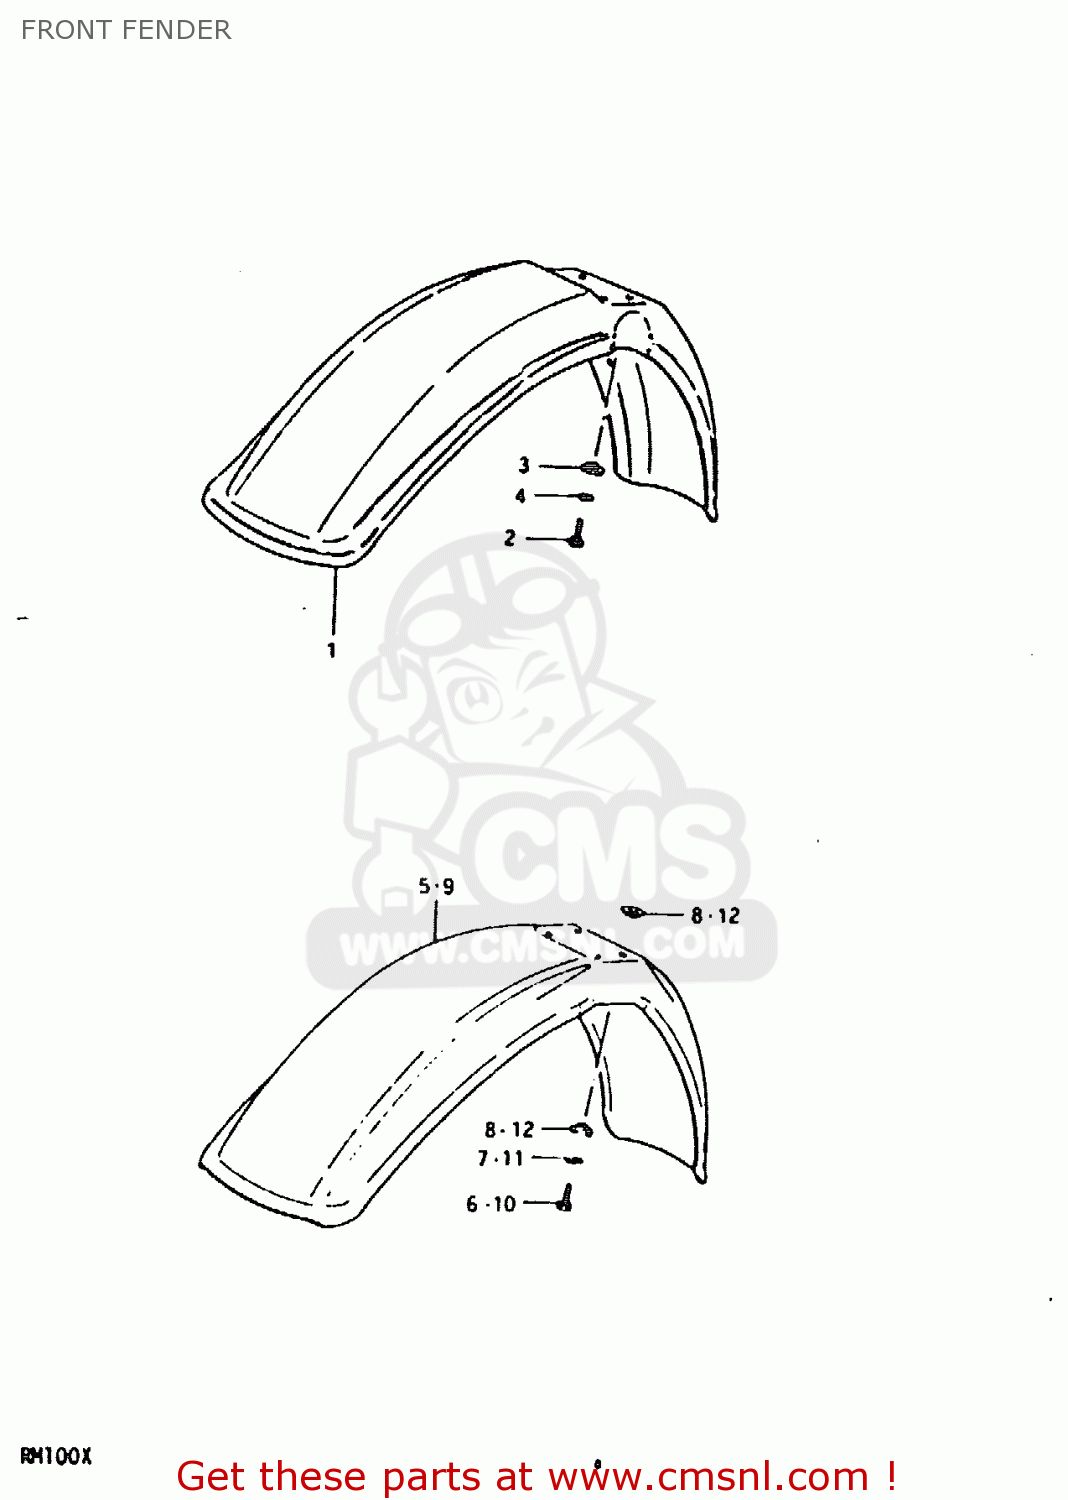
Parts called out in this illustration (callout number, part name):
1	FENDER,FRONT
2	BOLT, UPPER
3	SPACER
4	LOCK WASHER
5	FENDER,FRONT
6	BOLT, UPPER
7	LOCK WASHER
8	WASHER
9	FENDER,FRONT
10	BOLT, UPPER
11	LOCK WASHER
12	WASHER
